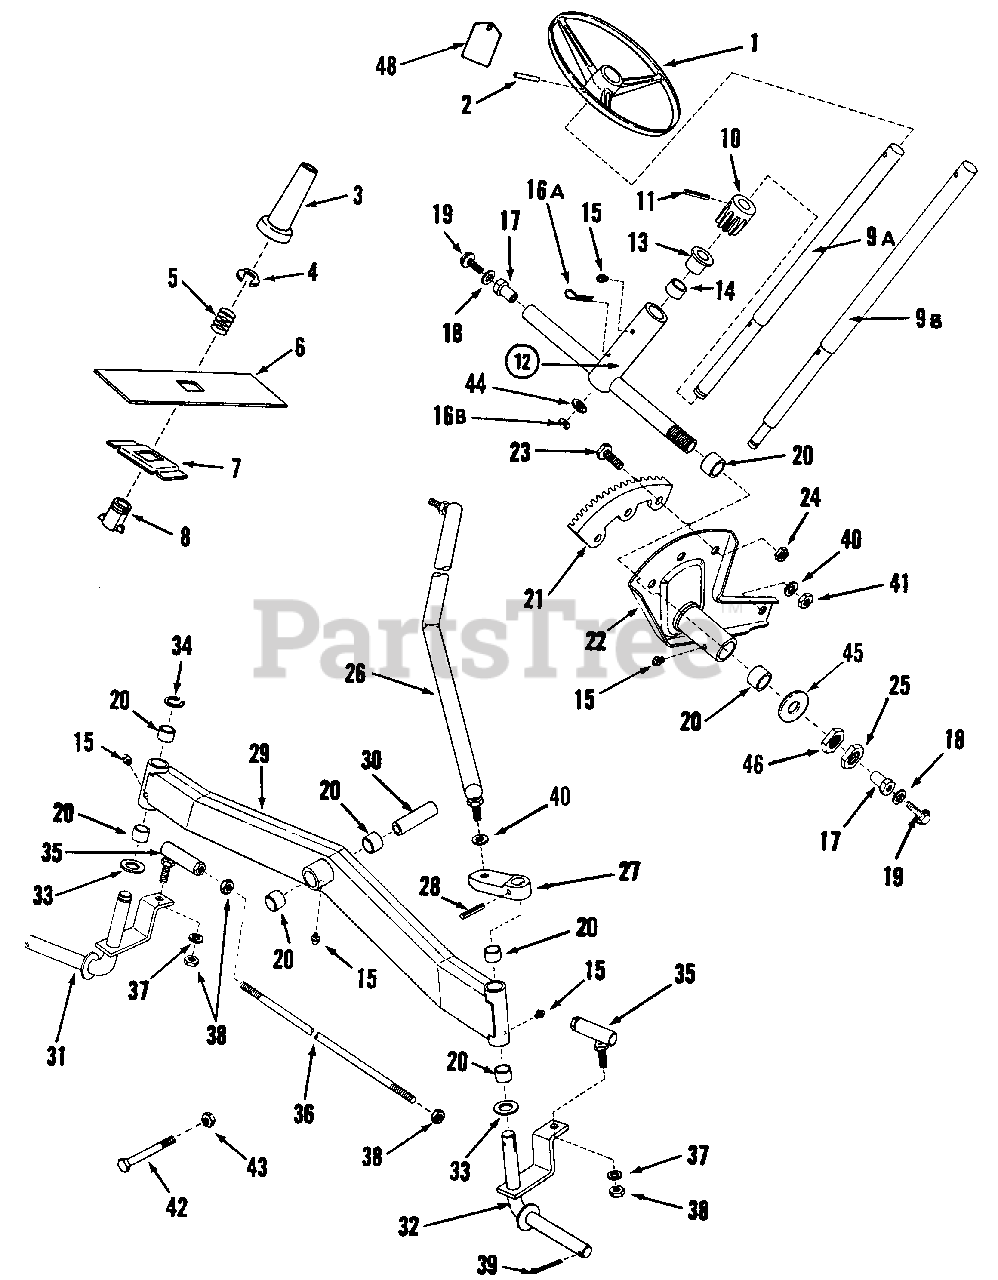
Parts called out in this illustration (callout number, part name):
1	STEERING WHEEL
2	ROLL-PIN, 1/4" x 2-1/4"
3	ACTUATOR, Steering Lock
4	RING, 13/16" External Retaining
5	SPRING, Actuator
6	COVER, Slide
7	RISER, Steering Lock
8	BUSHING, Steering Lock
9A	SHAFT, Steering (Early Models)
9B	SHAFT, Steering (Current Models)
10	PINION, Steering
11	ROLL-PIN, 3/16 x 1-1/2"
12	ASSEMBLY, Bearing Support
13	BEARING, Flange
14	BUSHING
15	LUBE FITTING, Straight (press-fit for .187 dia. Hole)
16A	HAIR-PIN (Early Models)
16B	SNAP-RING, 5/16 (Current Models)
17	PIVOT
18	WASHER, 5/16 Internal Tooth Lock
19	SCREW, 5/16-18 x 3/4" Hex Washer Self-Tap
20	BEARING
21	QUADRANT, Steering
22	ASSEMBLY, Sector
23	SCREW, 1/4-20 x 5/8" Hex Head Cap, Grade 5
24	NUT, 1/4-20 Hex Center Lock, Grade B or 5
25	NUT, 3/4-16 Hex Jam
26	DRAG-LINK
27	ARM, Steering
28	ROLL-PIN, 1/4 x 1-1/4"
29	ASSEMBLY, Front Axle
30	JOURNAL, Axle
31	KING-PIN, Right Side
32	KING-PIN, Left Side
33	WASHER, Thrust
34	RING, 3/4" External Retaining
35	BALL JOINT, 3/8-24 Thread
36	TIE-ROD
37	WASHER, 3/8" Split Lock
38	NUT, 3/8-24 Hex, Grade 2
39	COTTER-PIN, 5/32 x 1"
40	WASHER, 1/2 Split Lock
41	NUT, 1/2-20 Hex, Grade 2
42	SCREW, 1/2-20 x 4" Hex Head Cap, Grade 5
43	NUT, 1/2-20 Hex Thin Lock
44	WASHER, 3/8" Flat
45	WASHER, 3/4" I.D. Flat
46	NUT, 3/4-16 Hex
